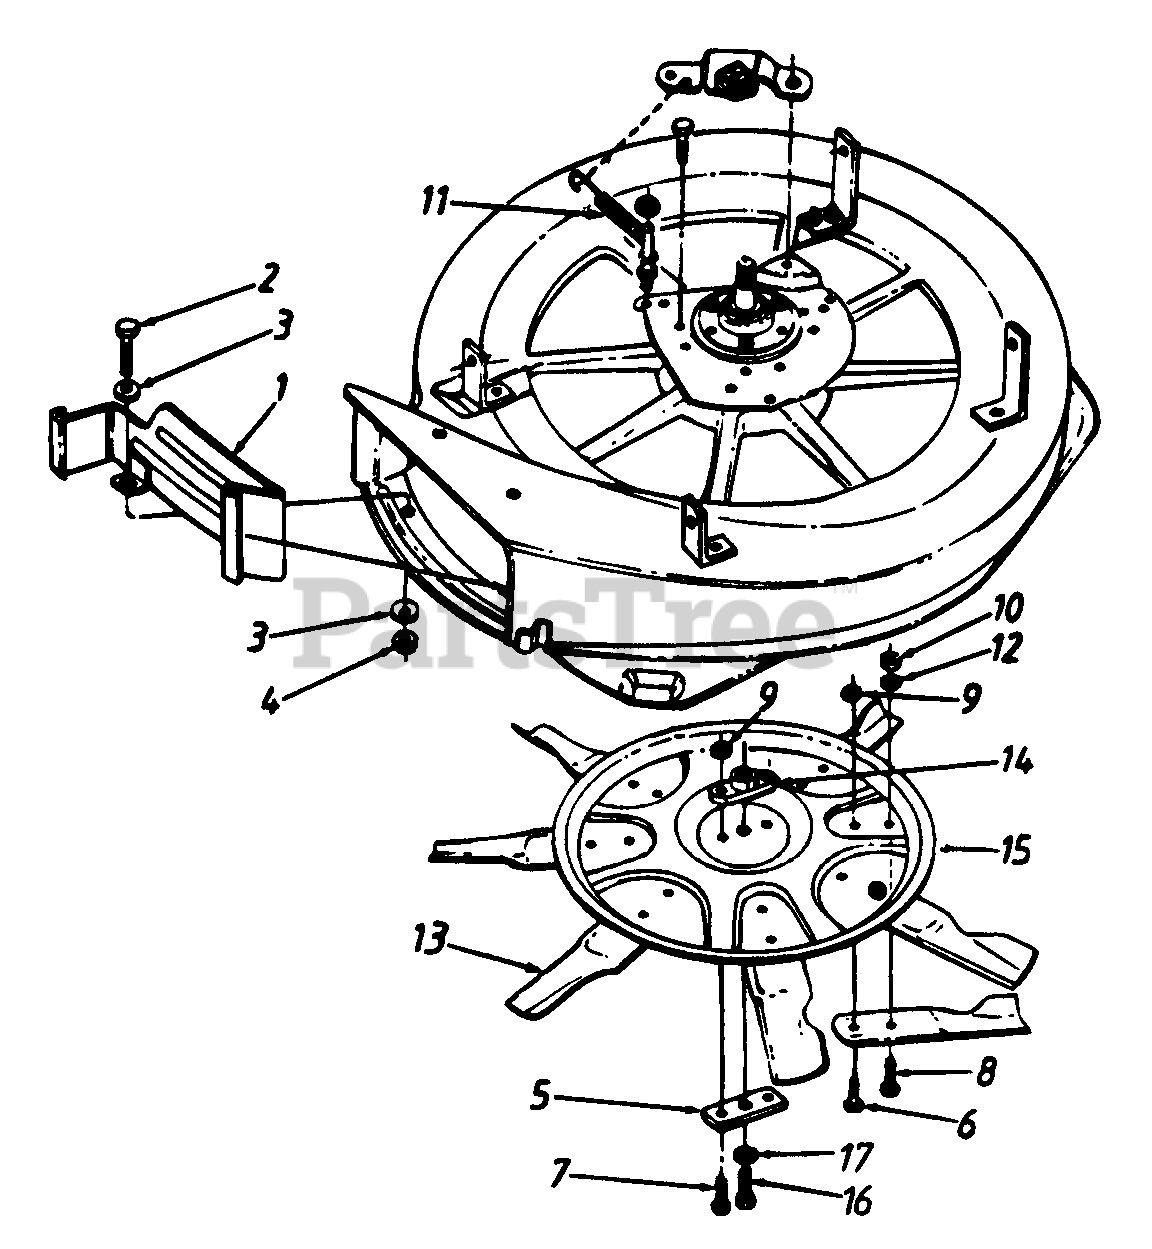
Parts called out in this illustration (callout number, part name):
1	Mulching Baffle Ass'y.
2	Hex Bolt 5/16-18 x .5"
3	Bell-Wash. .325" I.D.
4	Hex L-Nut 5/16-18 Thd.
7	Hex Bolt 5/16-24 x 1.25" Lg. (Gr. 5)
8	Hex Bolt 3/8-24 x .88" Lg.
9	Hex L-Nut 5/16-24 Thd.
10	Hex L-Nut 3/8-24 Thd. (Gr. 5)
11	Extension Spring 3.2" Lg.
12	Fl-Wash. .406" I.D. x .75"
13	30" Mulching Blade Tip
14	Blade Adapter
15	30" Mulching Blade Disc
16	Hex Bolt 3/8-24 x 1.25" Lg. (Gr. 8)
17	L-Wash. 3/8" I.D.
